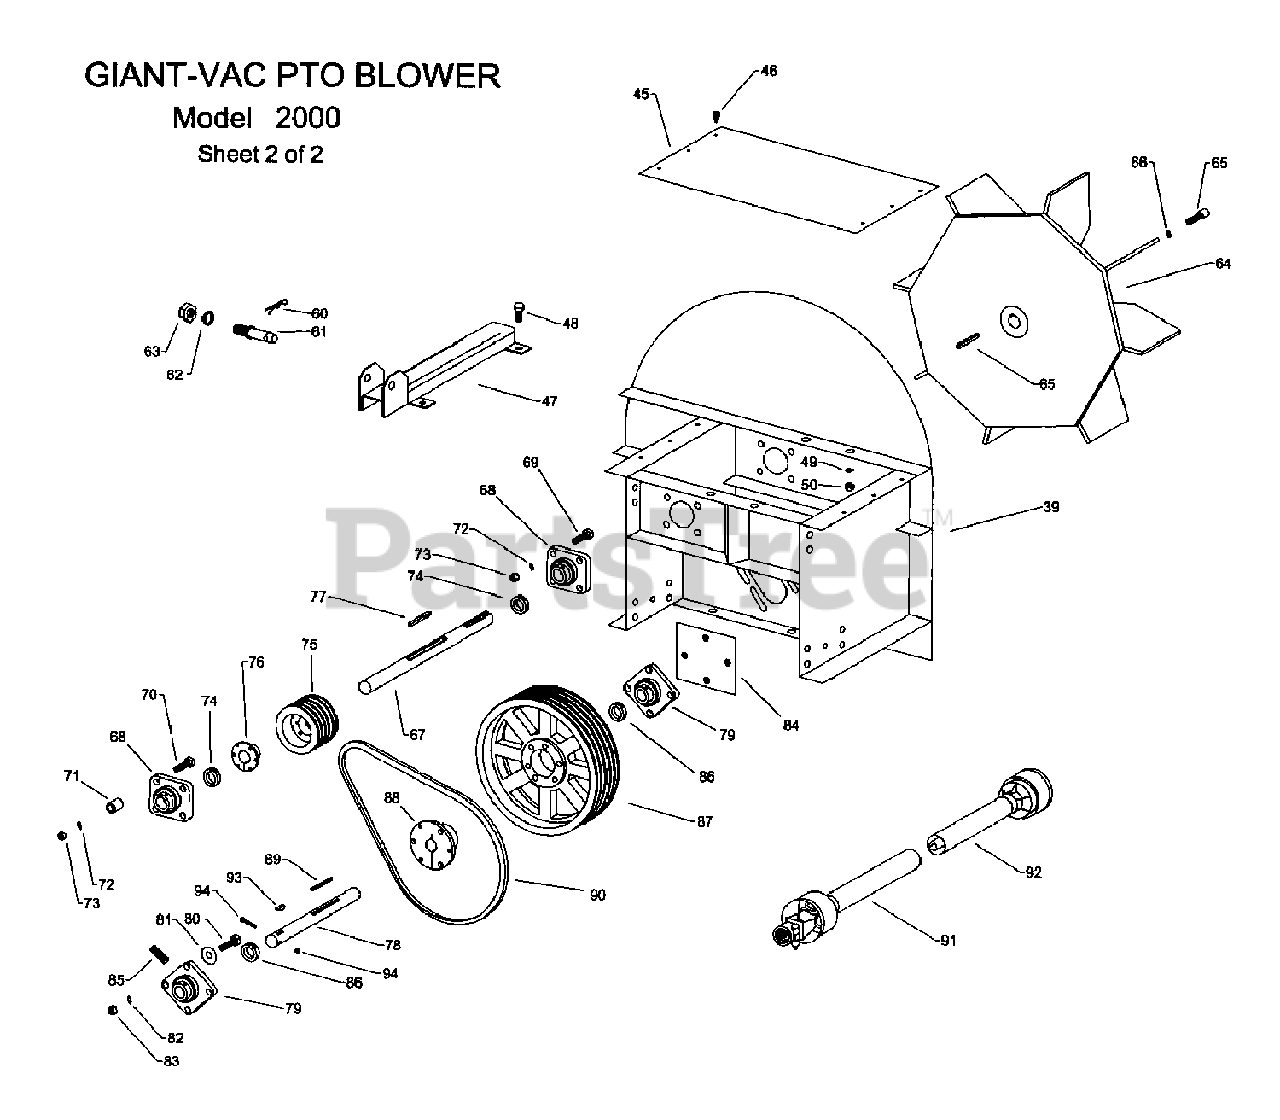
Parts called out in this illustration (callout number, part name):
45	Shaft frame top cover plate
46	#12 x 3/4 self tapping screw
47	Top hitch point bracket
48	1/2 x 1-1/4 hex bolt
49	1/2 lockwasher
50	1/2 hex nut
60	Jack stand hair clip
61	Hitch pin
62	7/8 hitch pin nut
63	7/8 hitch pin lockwasher
64	Impeller, 22"
65	Impeller bolt & key (5/8 x 3)
66	5/8 lockwasher
67	Impeller shaft
68	Impeller shaft bearing
69	1/2 x 1-3/4 hex bolt (impeller shaft inner bearing)
70	1/2 x 2-1/2 hex bolt (impeller shaft outer bearing)
71	Impeller shaft outer bearing spacer
72	1/2 lockwasher
73	1/2 hex nut
74	Impeller shaft collar
75	Impeller shaft pulley
76	Impeller shaft pulley hub ass’y (w/hardware)
77	Key - 3/8 x 3-1/2
78	Lower input shaft
79	Lower input shaft bearing
80	1/2 x 1-3/4 hex bolt
81	1/2 flatwasher
82	1/2 lockwasher
83	1/2 hex nut
84	Lower input shaft inner bearing bolt plate
85	1/2 x 4 Allen head pusher bolt
86	Lower input shaft locking collar
87	Lower input shaft pulley
88	Lower input shaft pulley hub ass’y (w/hardware)
89	Key - 1/4 x 2-1/4
90	Drive belts (4 to a set)
91	Drive shaft - tractor end*
92	Drive shaft - unit end*
93	5/16 drive shaft key
94	¼ x 2-1/2 bolt & nut
